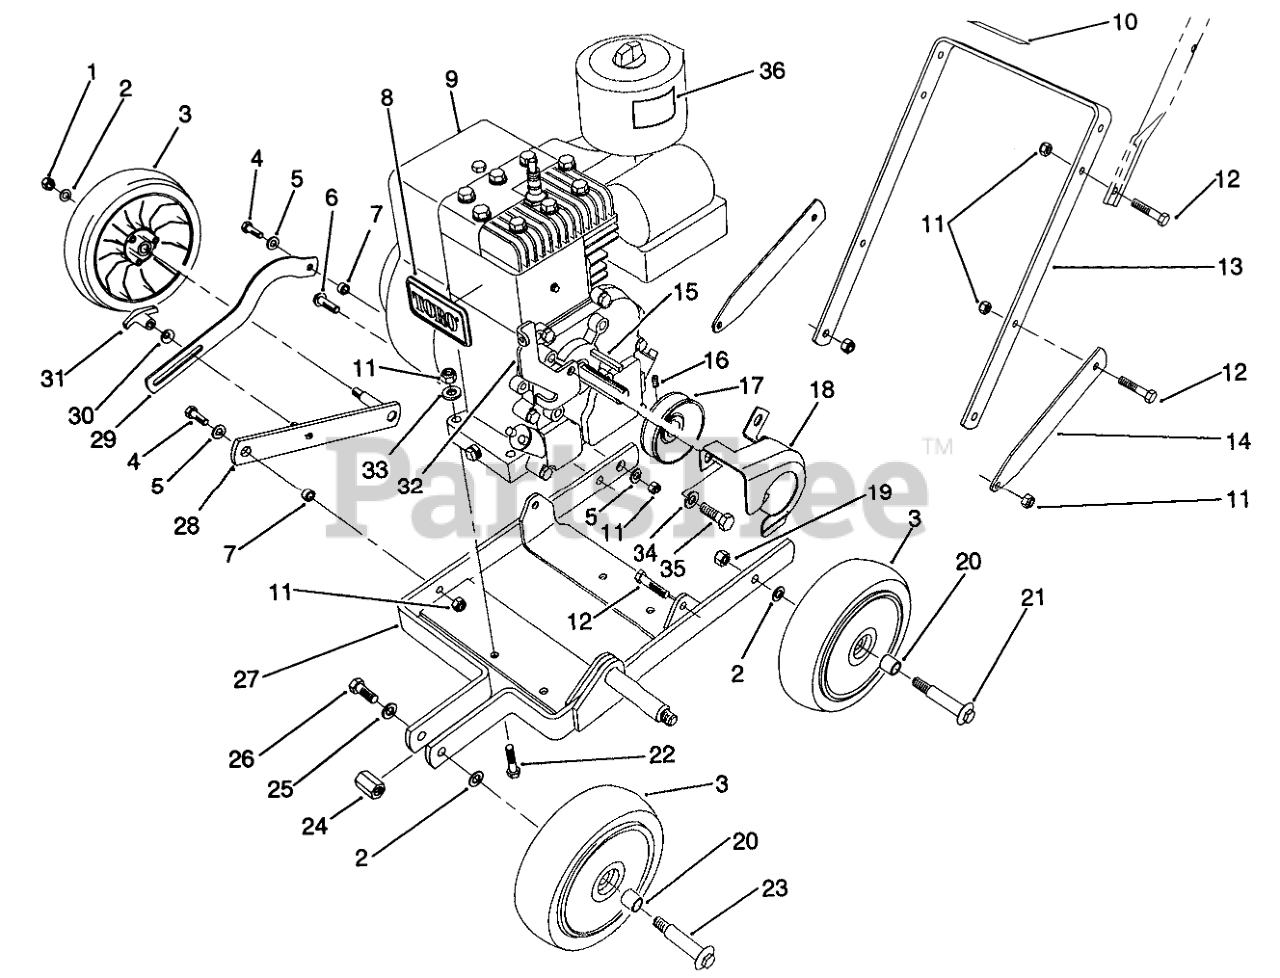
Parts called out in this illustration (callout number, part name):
1	NUT-LOCK
2	WASHER
3	Wheel & Tire Assembly (Incl. Ref. #20)
4	SCREW-HH
5	WASHER-FLAT
6	3/8-24 X 1.00HEX BU. HD
7	WHEEL MT BUSHING
8	TORO LOGO PLT
10	DECAL-WARNING
11	NUT-LOCK, NI
12	SCREW-HH
13	LOWER HANDLE
14	SUPPORT HANDLE
16	SCREW-SET
17	2HP PULLEY
18	ENG. PULLEY GUARD
19	NUT-HEX
20	BUSHING
21	WHEEL BOLT
22	SCREW-HH
23	BOLT-WHEEL
24	HEX SPACER
25	WASHER-LOCK
26	SCREW-HH
27	Frame-Edger
28	WHEEL MOUNT WA
29	AXLE LINK
30	BELLEVILLE SPRING WASHE
32	SPRING BRACKET
33	WASHER-PLAIN
34	WASHER-LOCK
35	SCREW-HH
36	DECAL-SURFACE, HOT
